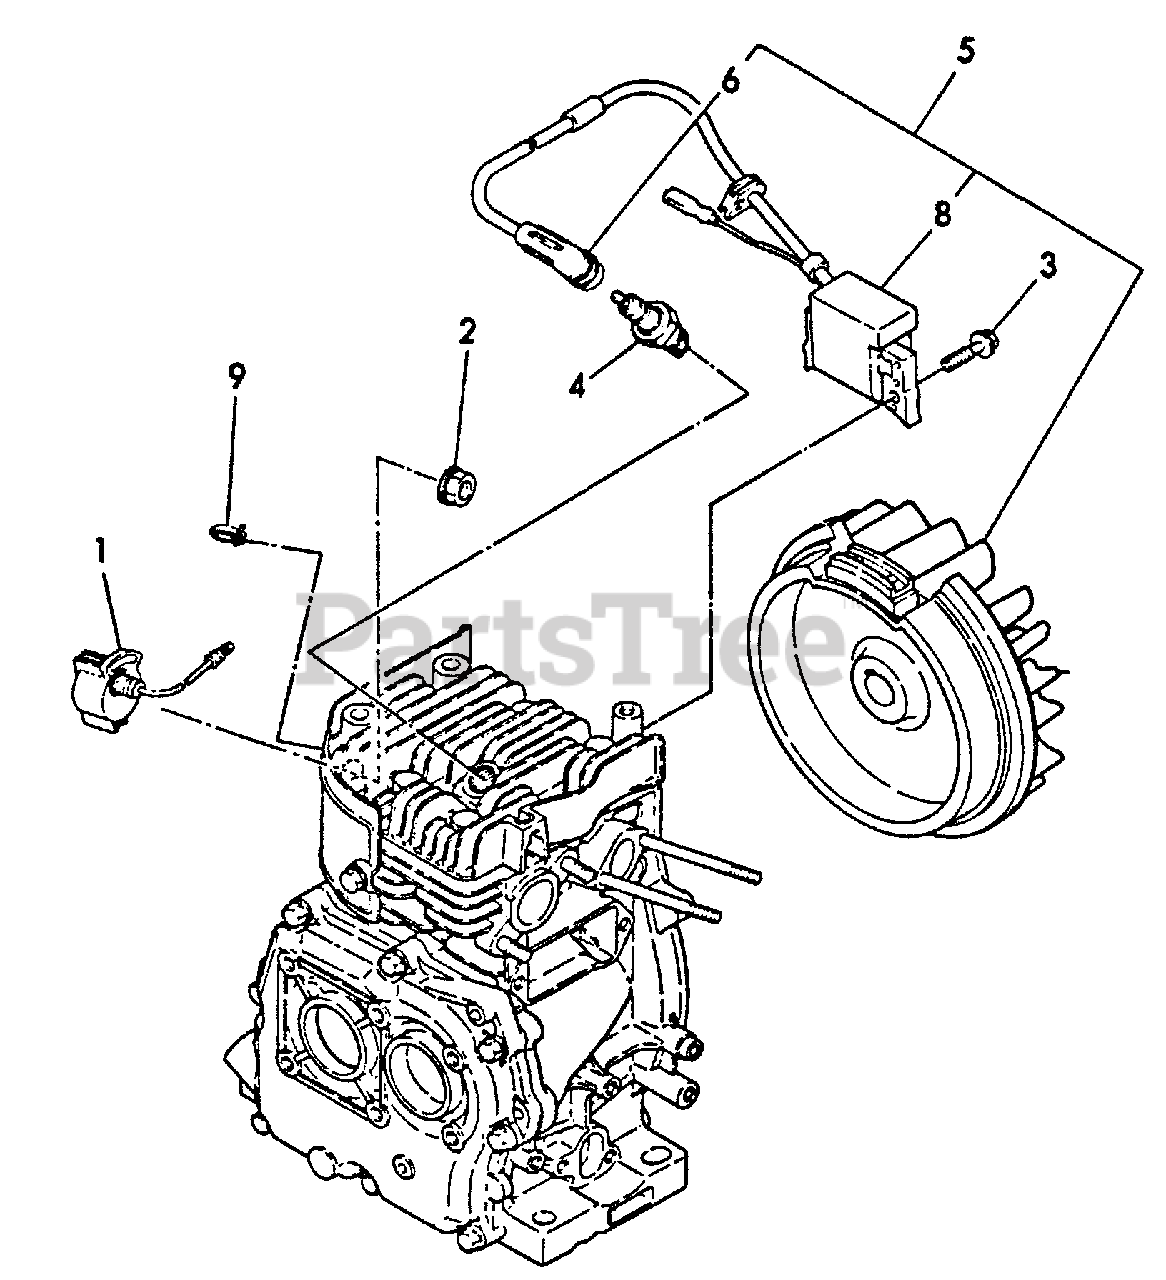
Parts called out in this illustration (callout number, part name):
1	IGNITION SWITCH ASSY
2	NUT - 8
3	BOLT - 6X25
4	SPARK PLUG
5	FLYWHEEL
6	CAP, PLUG
8	COIL, IGNITION
9	CLAMP
